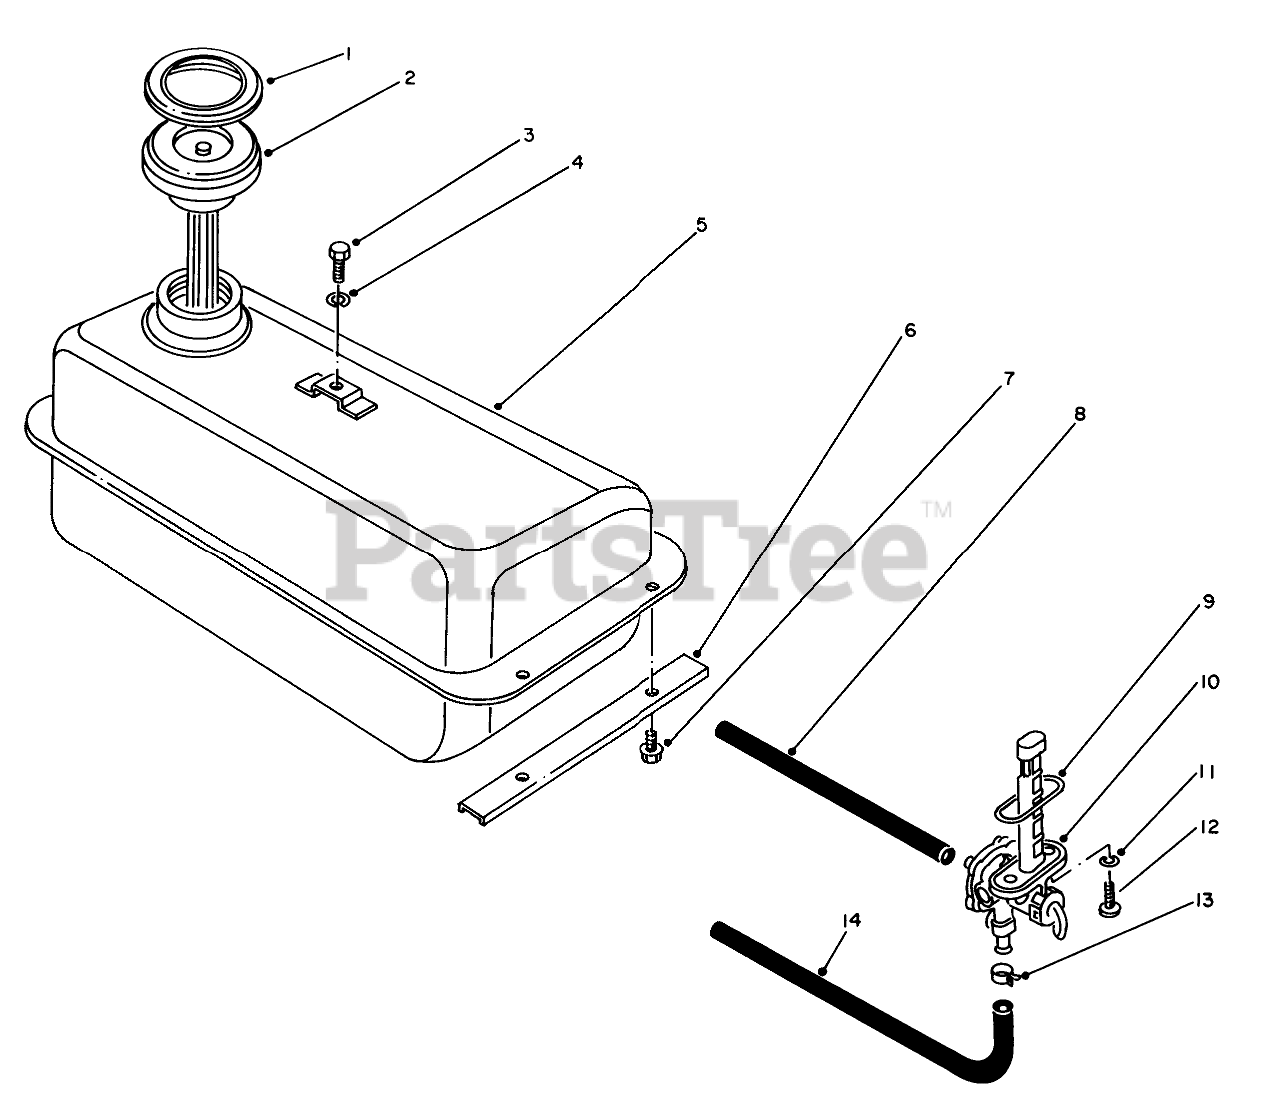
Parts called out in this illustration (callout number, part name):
1	Grommet
2	Gas Cap Assembly
4	Washer
5	FUEL TANK ASY
6	Clamp-Fuel Tank
9	0-Ring
10	Cock Assembly-Fuel (Incl. Ref. #9)
11	GASKET (6.2X11X1)
12	Screw
